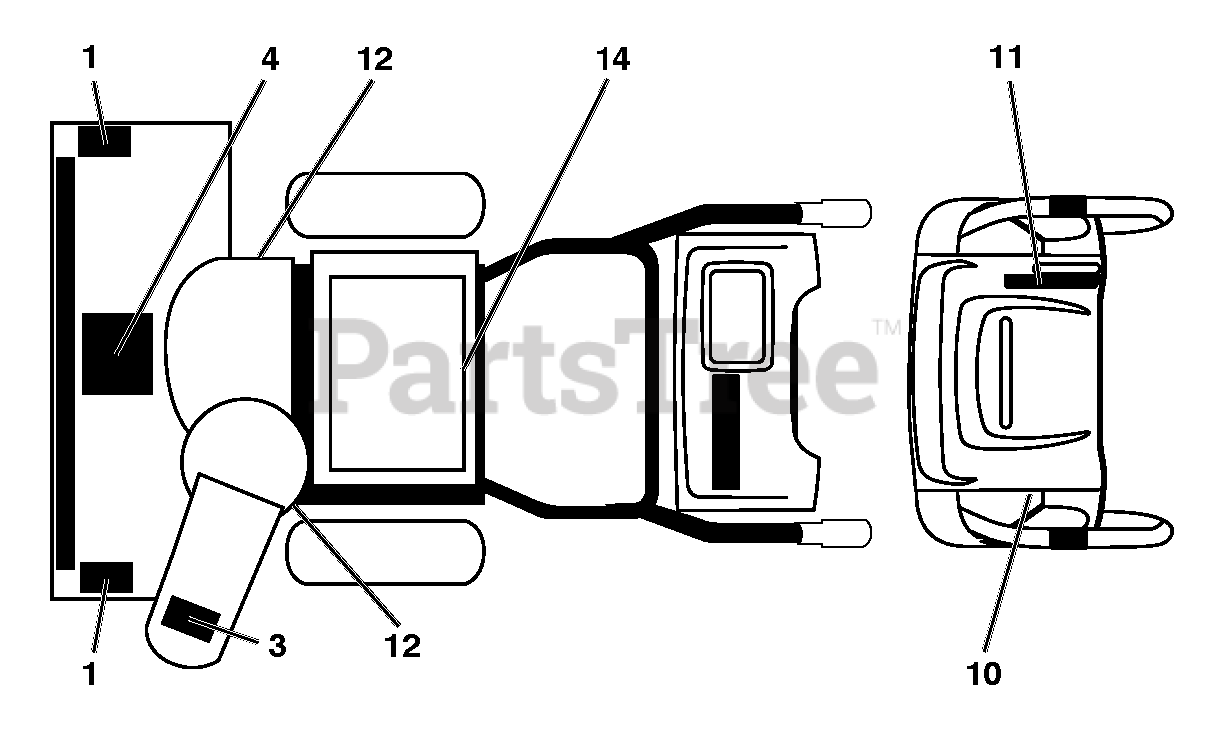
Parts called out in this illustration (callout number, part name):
1	DECAL.AUGER.SAFETY.
3	DECAL.CHUTE.SAFETY.
4	DECAL.AUGER."
10	DECAL.CONS.LT.SPD/LEV/PWRST.
11	DECAL.CONS.RT.SPD/LEV/PWRST.
12	DECAL.BELT.GUARD.
14	DECAL.FENDER
